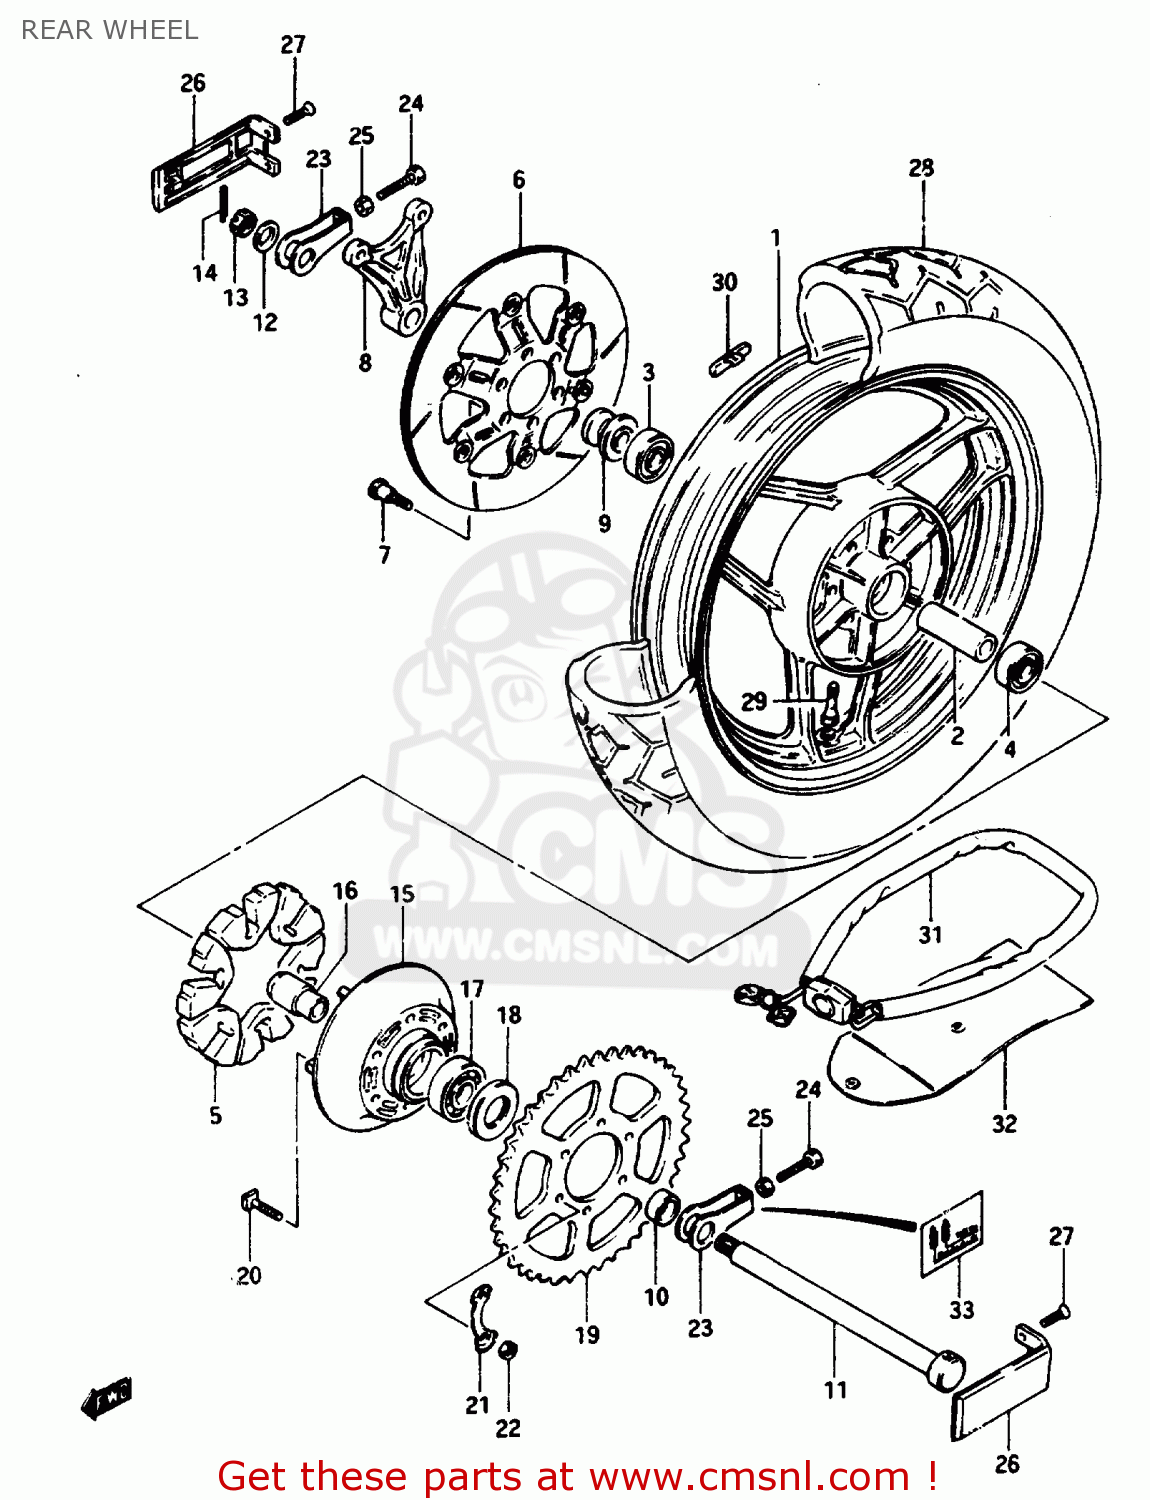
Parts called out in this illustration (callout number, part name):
1	CASTING WHEEL,REAR 3.00
2	SPACER (20.5X28X83)
3	BEARING WHEEL REAR(20X47X14)
4	BEARING, LH
5	ABSORBER,REAR HUB SHOCK
6	DISC,REAR BRAKE
7	BOLT
8	BRACKET,RR,CALIPER
9	SPACER,RR AXLE,R
10	SPACER (20X33X13.3)
11	AXLE,REAR
12	WASHER (19X32X2.6)
13	NUT 18MM
14	PIN,COTTER
15	DRUM,REAR SPROCKET MOUNT
16	SPACER,REAR HUB BEARING
17	BEARING
18	SEAL,OIL(33X62X7)
19	SPROCKET,REAR
20	BOLT(10X35.5)
21	WASHER
22	NUT
23	ADJUSTER CHAIN
24	BOLT 8X50
25	NUT
26	COVER,CHAIN ADJUSTER
27	SCREW 5X16
28	TIRE, T/L REAR (130/90V17) BS
29	VALVE,TIRE
30	BALANCER,WHEEL
31	CHAIN LOCK ASSY
32	BAG,CHAIN LOCK
33	LABEL,CHAIN WEAR INDICATOR
